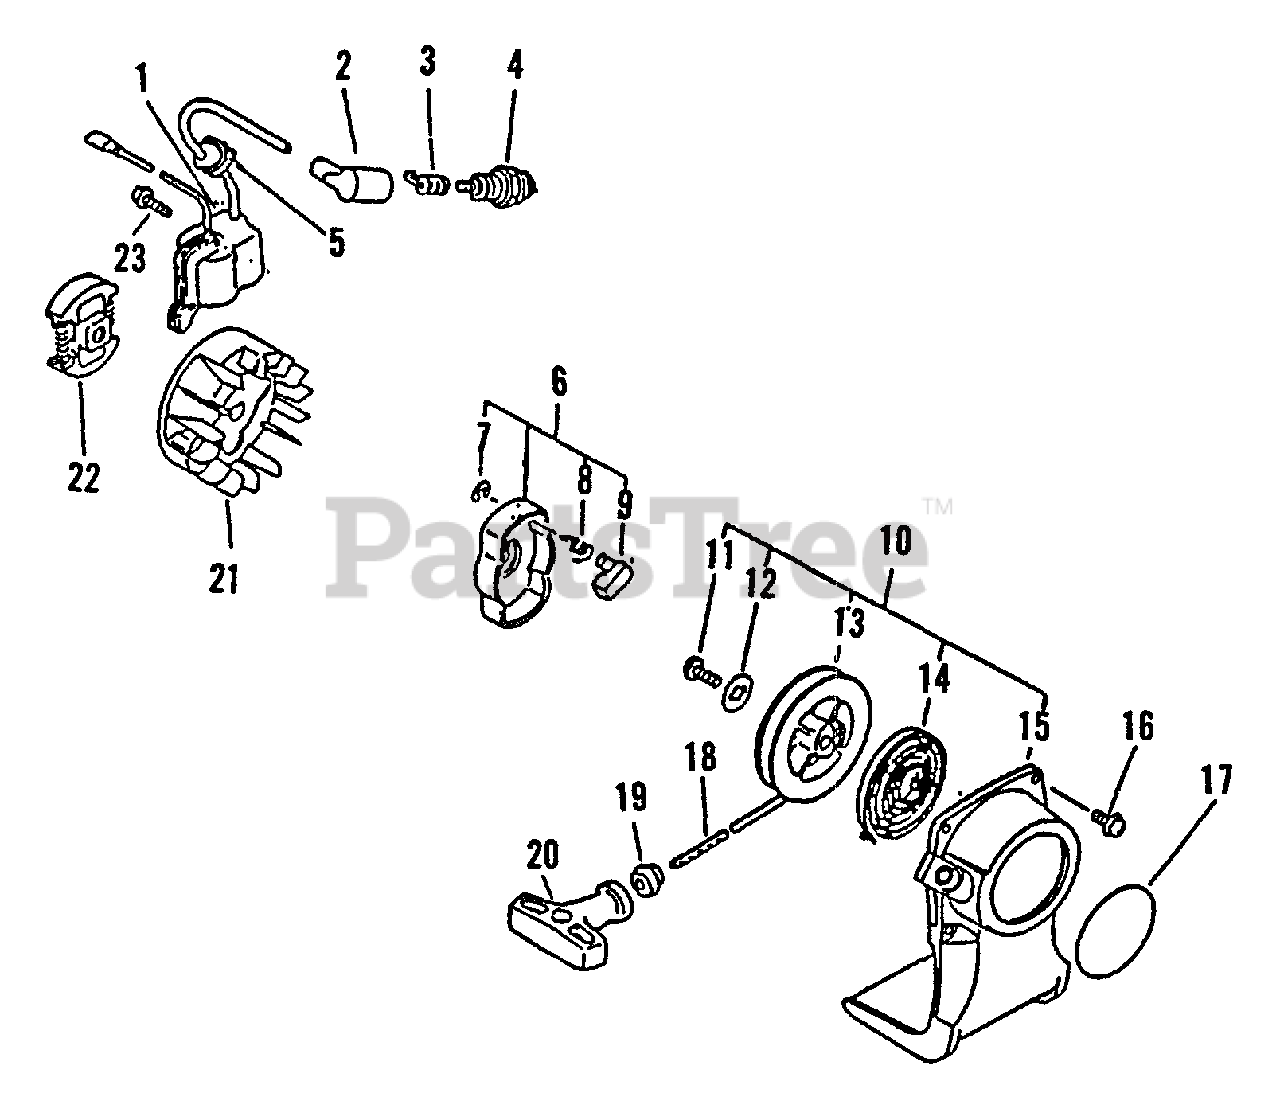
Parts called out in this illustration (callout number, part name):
1	COIL, IGNITION
2	CAP, SPARK PLUG
3	TERMINAL, SPARK PLUG
4	SPARK PLUG - BPM7A
6	STARTER PAWL ASSY
7	E-RING 4
8	SPRING, RETURN
9	PAWL, STARTER
10	STARTER ASSY
12	WASHER
13	REEL, ROPE
14	SPRING, RECOIL
15	CASE, STARTER - BLUE
16	SCREW 4×16
17	LABEL, ECHO
18	ROPE, STARTER
19	GUIDE, ROPE
20	GRIP, STARTER
21	FLYWHEEL
22	CLUTCH ASSY
23	SCREW 4×22
